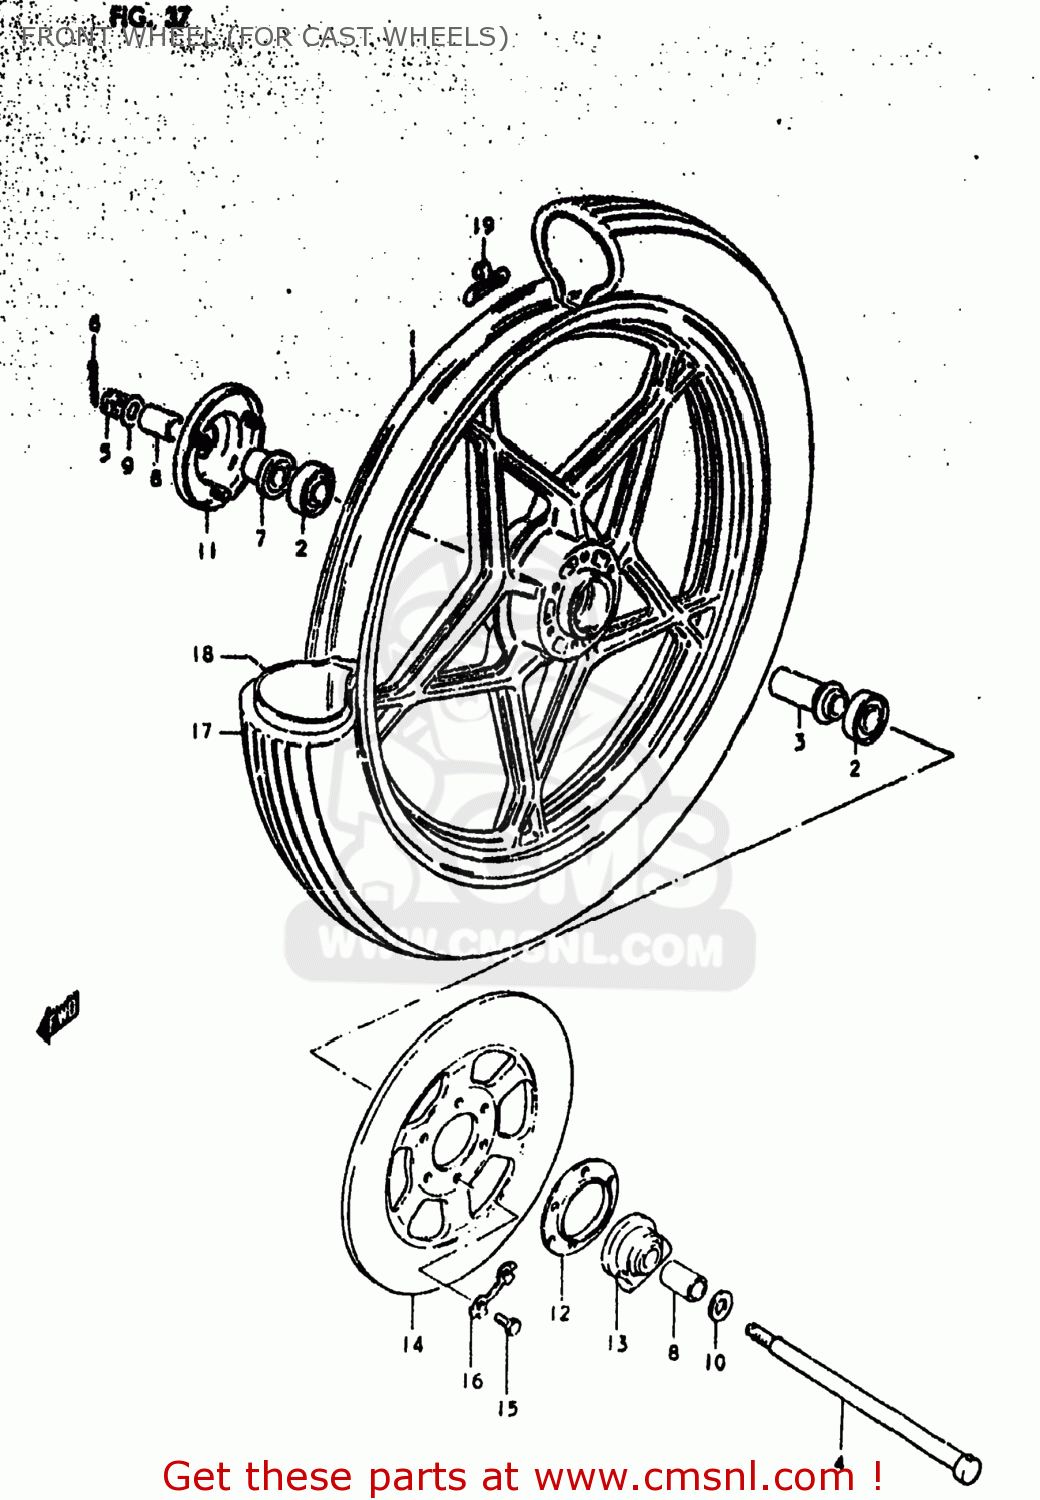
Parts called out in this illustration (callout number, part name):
1	WHEEL, FRONT
2	BEARING
3	SPACER,FR HUB BEARING
4	AXLE,FRONT
5	NUT 12MM
6	COTTER PIN
7	SPACER,FR AXLE,R
8	SPACER(15X22X30)
9	WASHER
10	WASHER
11	COVER,FR HUB,R
12	DUST SEAL,SPEEDOMETER GEAR BOX
13	BOX ASSEMBLY,SPEEDOMETER GEAR
14	DISC,BRAKE
15	BOLT(8X25)
16	WASHER
17	TIRE,FRONT
18	TUBE,INNER
19	BALANCER,WHEEL
